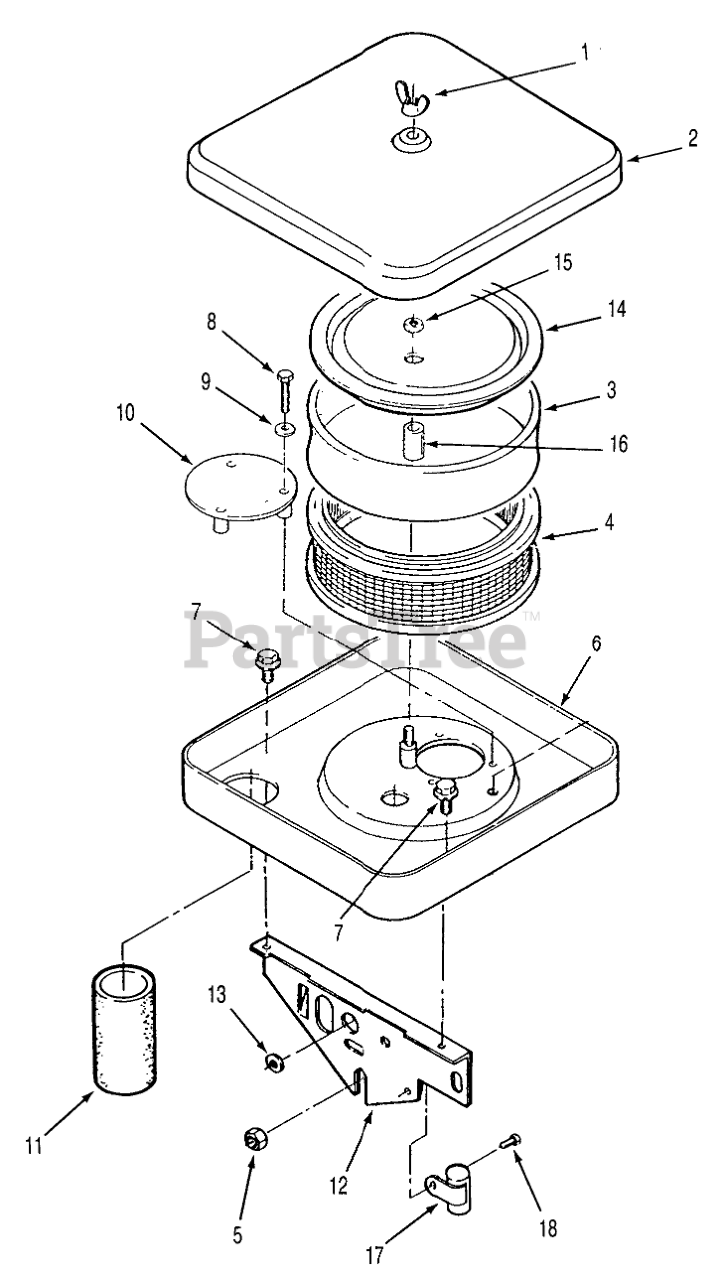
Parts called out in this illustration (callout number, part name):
1	Nut-Wing
2	AIR CLEANER COVER
3	AIR CLEANER ELEMENT
4	Air Cleaner Element
5	Nut
6	Air Cleaner Housing
7	Screw 1/4-20 x 3/8
8	Screw Hex Hd. #10-32 x 1-1/2
9	Flat Washer #10
10	AIR DEFLECTOR PLATE
11	AIR INTAKE TUBE
12	AIR CLEANER SUPPORT
13	Grommet
14	Element Cover
15	Hex Nut 1/4-20
16	Spacer
17	Condenser
18	SCREW #10-32 X 5/8
